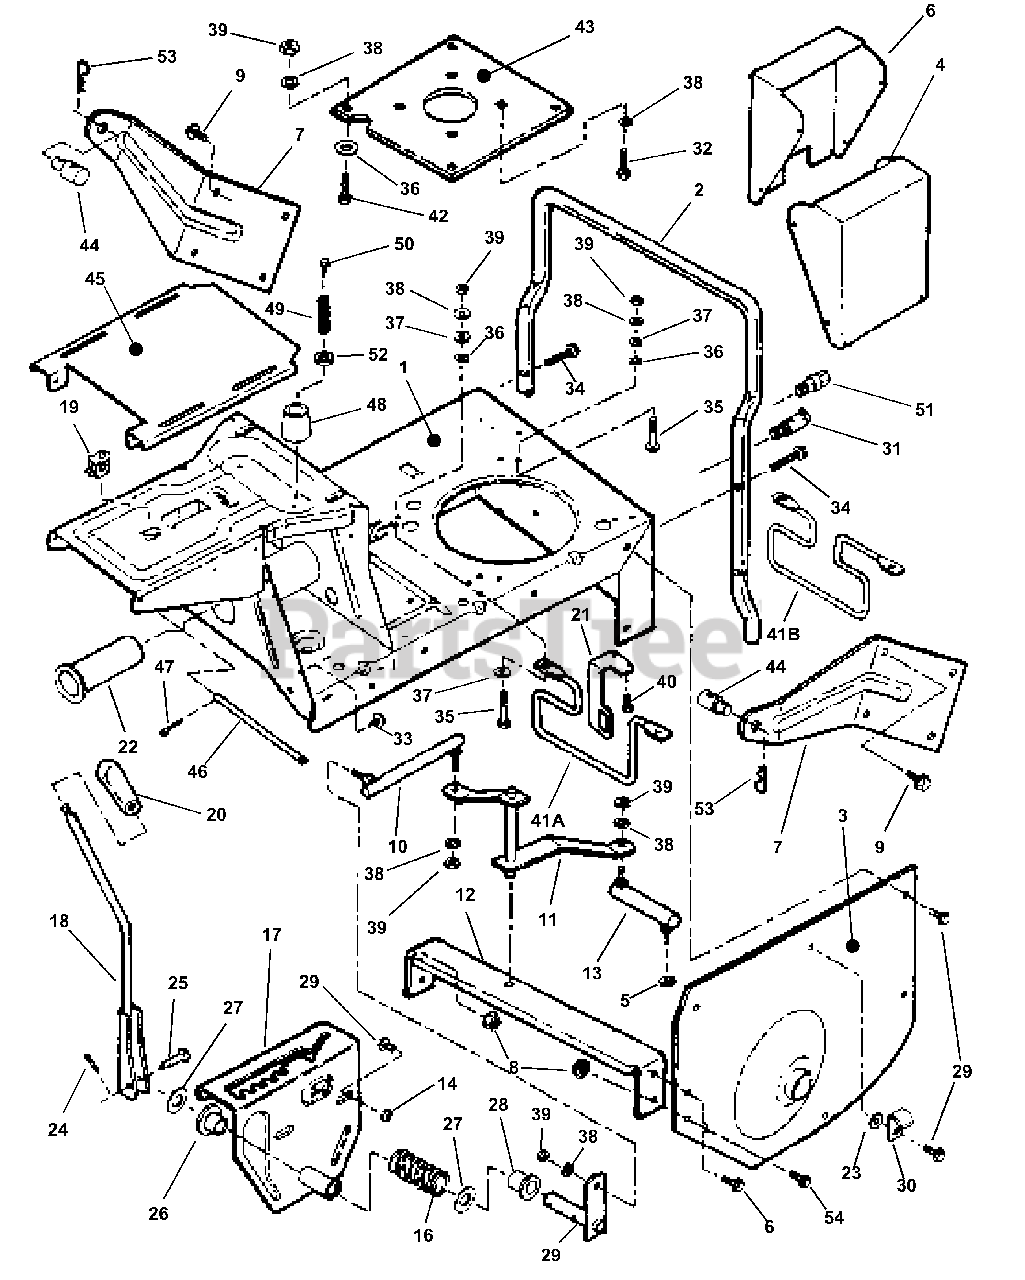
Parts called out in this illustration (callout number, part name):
1	CASE, Main (13 HP Briggs)
2	BUMPER, Rear
3	FENDER, Left Hand
4	COVER, Battery
5	NUT, 5/16-24 Hex Flange Lock
6	COVER, Switch
7	WING, Rear (Models 28" & 33" Only!)
8	NUT, 5/16-18 Hex Fl. Lock
9	SCREW, 5/16-18 x 3/4" Hex Washer Self-Tap
10	LINK, Shift (Long)
11	ARM, Shift
12	BRACE, Cross
13	LINK, Shift (Short)
14	NUT, 5/16-18 Hex
16	SPRING, Shift Handle
17	DETENT, Shift
18	HANDLE, Shift
19	SWITCH, Seat
20	KNOB, Shift Handle
21	BRACKET, Switch
22	BUSHING, Pilot
23	WASHER, 5/16 Internal Tooth Lock
24	PIN, 3/32 x 3/4" Cotter
25	PIN, 1/4 x 1-3/4" Tapered Clevis
26	BUSHING, Nylon
27	WASHER, Thrust
28	BUSHING, Nylon
29	SCREW, 5/16-18 x 5/8" Hex Washer Self-Tap
30	CLIP, Wire (7/16")
31	DRAIN, Oil (1/4 Turn) (Kohler)
32	BOLT, M8-1.25 x 25mm, Self-Tap (Kohler)
33	FASTENER, 1/4 x 3/4 Ratchet
34	SCREW, 5/16-18 x 1-1/2" Hex Washer Self-Tap
35	SCREW, 5/16-24 x 1-3/4" Hex Head Cap, Grade 5
36	RETAINER, 5/16 Bolt
37	WASHER, 5/16" Flat
38	WASHER, 5/16" Split Lock
39	NUT, 5/16-24 Hex
40	SCREW, #10-24 x 1/4" Hex Washer Self Tap
41A	GUIDE, Belt (33" Kohler)
41B	GUIDE, Belt (28" Briggs)
42	SCREW, 5/16-24 x 1" Hex Head Cap, Grade 5
43	PLATE, Engine
44	SWIVEL
45	PLATE, Seat
46	PIN, Hinge
47	PIN, 1/16 x 3/4", Cotter
48	CUSHION
49	SPRING, Seat O.P.C.
50	SCREW, 1/4-20 x 5/8" Self-Tap, Truss Head, Torx
51	DRAIN, Oil (Briggs)
52	WASHER, 9/32" I.D. x 5/8" O.D.
53	HAIRPIN, 3/32 x 1-1/2"
54	SCREW, 5/16-18 x 3/4" Hex Head Cap, Grade 5
